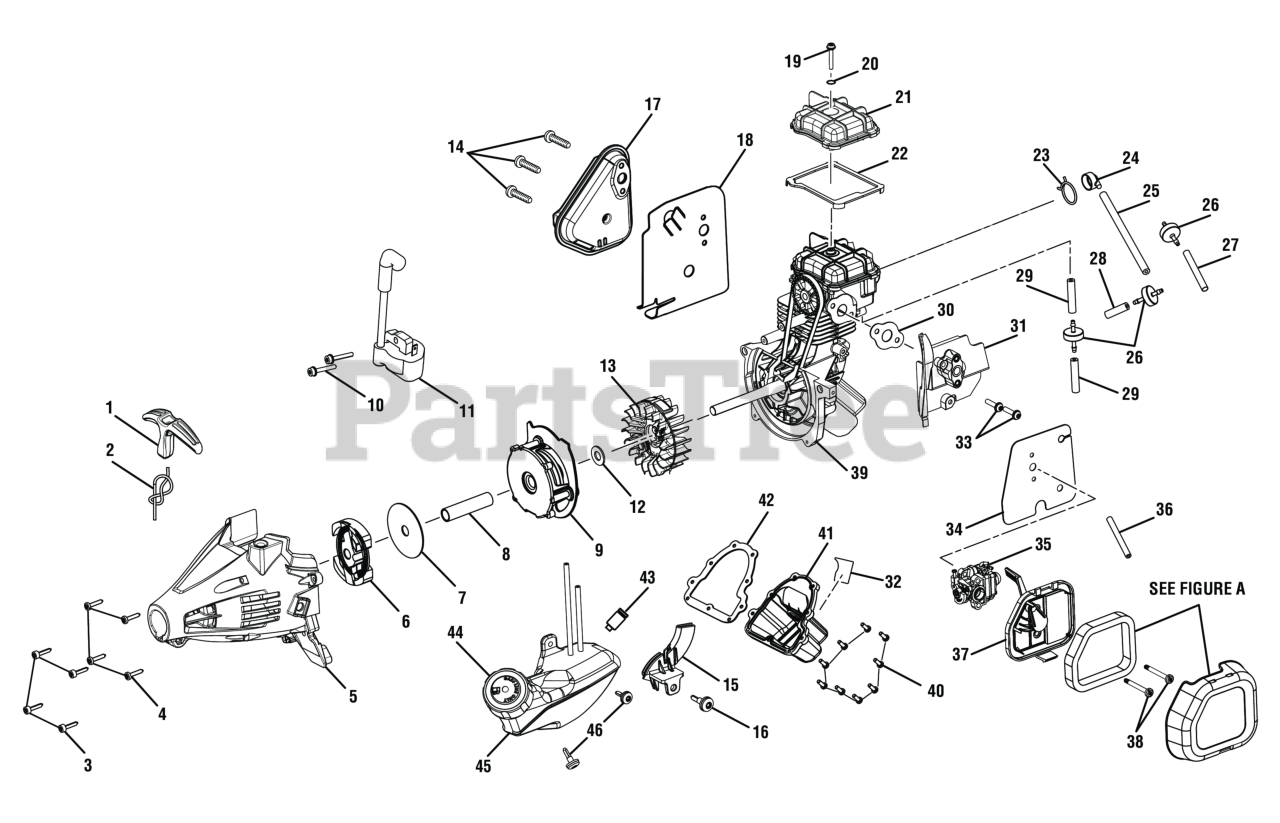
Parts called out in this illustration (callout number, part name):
1	Starter Grip
2	STARTER ROPE 42 (PKG)
3	Screw (M4 x 18 mm, T20 Torx Pan Hd. S.T.)
4	Screw w/Washer (M4 x 16 mm, T25 Torx Truss Hd.)
5	Starter Housing Assembly
6	CLUTCH ASSEMBLY
7	Washer (ID9.63 x OD50.75 x 1.10t)
8	Spacer Tube
9	Starter Housing Assembly
10	Screw w/Washer (M4 x 19 mm, T20 Torx Pan Hd. S.T.)
11	Ignition Module
12	Washer (ID9.75 x OD20 x 1.6t)
13	Flywheel Assembly
14	Screw (M5 x 38 mm, T25 Torx Truss Hd.)
15	Throttle Cable Guide
16	Shoulder Screw (M4 x 19 mm, T25 Torx Truss Hd.)
17	Muffler Assembly
18	Muffler Gasket
19	Screw (M4 x 27 mm Total, w/14 mm Threaded)
21	Cam Cover
22	Cam Cover Gasket
23	Wire Clamp
24	Breather Fitting
25	Breather Hose (120 mm)
26	Check Valve
27	Shield Sleeve (M6 x 50 mm)
28	Breather Hose (24 mm)
29	Breather Hose (34 mm, Crankcase)
30	Heat Dam Gasket
31	Heat Dam
32	Hot Surface Label
33	Screw (M5 x 23 mm, T25 Torx Pan Hd.)
34	Heat Shield w/Gasket (Carburetor)
35	Carburetor
36	Breather Hose (50 mm)
37	Air Box Base Assembly
38	Screw (M5 x 44 mm,T25 Torx Hd. Carburetor)
39	Short Block Assembly
40	Screw (M4 x 12 mm, T20 Torx Hd.)
41	Oil Pan (Inc. Key No. 47)
42	Oil Pan Gasket
43	Fuel Filter
44	Fuel Cap Assembly
45	Fuel Tank w/Cap (Inc. Key Nos. 43-44)
46	Shoulder Screw w/Washer (M4 x 14 mm, T25 Torx Truss Hd.)
